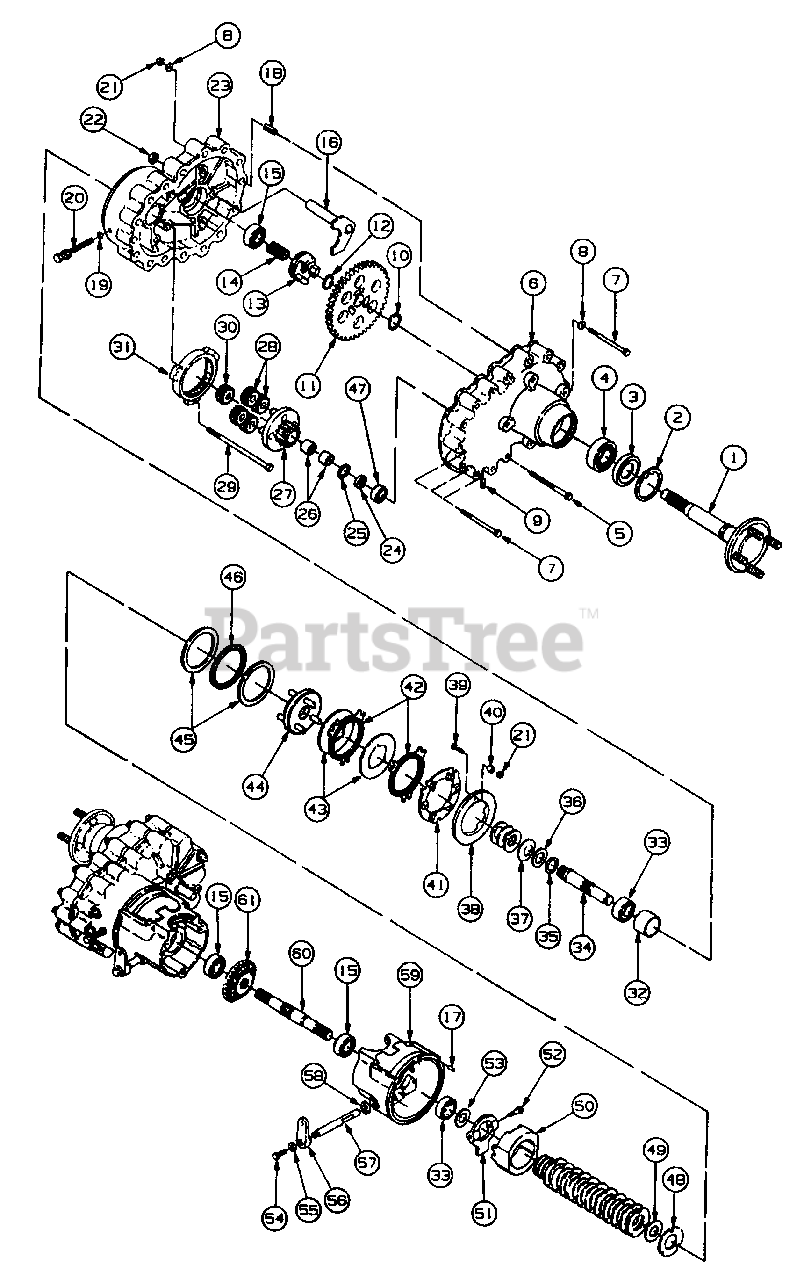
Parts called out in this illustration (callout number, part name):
1	Axle Assy
2	Ring, Inverted Retainer
3	Seal, Oil
4	Bearing
5	Screw, Hex Wash Hd Tapp 1/4-20 X 2.31 Lg
6	Housing, RH Outer Reduction
7	Screw, Hex Cap 1/4-20 X 4.0 Lg
8	Washer, Flat .25 X .62
9	Plug, Magnetic 1/2-14 NPTF
10	Ring, External Retainer
11	Gear, Axle Bull
12	Ring, Retainer 7/8 Shaft
13	Collar, Drive
14	Spring, Compression 1.095 OD X 1.75 Lg
15	Bearing
16	Shaft Assy, Neutral
17	Pin, Dowel, 3/16 Dia X .87 Lg
18	Pin, Slotted Spring 7/16 X 1.0 Lg
19	O-Ring, .208 ID X .070 Thk
20	Bolt, Brake Adjuster
21	Nut, Hex Top Lock, 1/4-20 GR 5
22	Seal, Oil, .500 X .750 X .125
23	Housing, RH Inner Reduction
24	Spacer, .6325 X .820 X .200
25	Washer, Flat .627 X 1.000 X .030 Thk
26	Bearing, Needle .625 X .812 X .495
27	Carrier Assy
28	Gear, Planet
30	Gear, Sun
31	Gear, Ring
32	Spacer, 1.500 X 1.815 X 1.271
33	Bearing, Angular Contact
34	Shaft, Output
35	Washer, Flat .915 X 1.37 X .010 Thk
36	Washer, Flat .88 X 1.50 X .030 Thk
37	Washer, Spring .882 X 1.77 X .49 Thk
38	Ramp, RH Brake
39	Screw, Hex Cap, 1/4-20 X .88 Lg
40	Spacer .254 ID X .05 OD X .390 Lg
41	Plate, RH Brake Adjustment
42	Disc, Friction
43	Disc, Brake
44	Hub Assy, Drive
45	Washer, Thrust 3.0 X 3.75 X .125 Thk
46	Bearing, Thrust 3.0 X 3.75 X .078 Thk
47	Ball, Bearing .625 X 1.574 X .470
48	Disk, Friction
49	Plate, Clutch
50	Hub, Brake
51	Arm, Brake Actuator
52	Bolt, Shoulder
53	Washer, Flat .760 X 1.50 X .036
54	Screw, Hex Cap 1/4-20 X .62 Lg GR 5
55	Washer, Belleville .265 X .75 X .062 Thk
56	Arm, Clutch/Brake
57	Shaft, Clutch/Brake Actuator
58	Seal, Oil, .625 X .812 X .094
59	Housing, RH Clutch/Brake
60	Shaft, Drive
61	Gear, Bevel 32T
